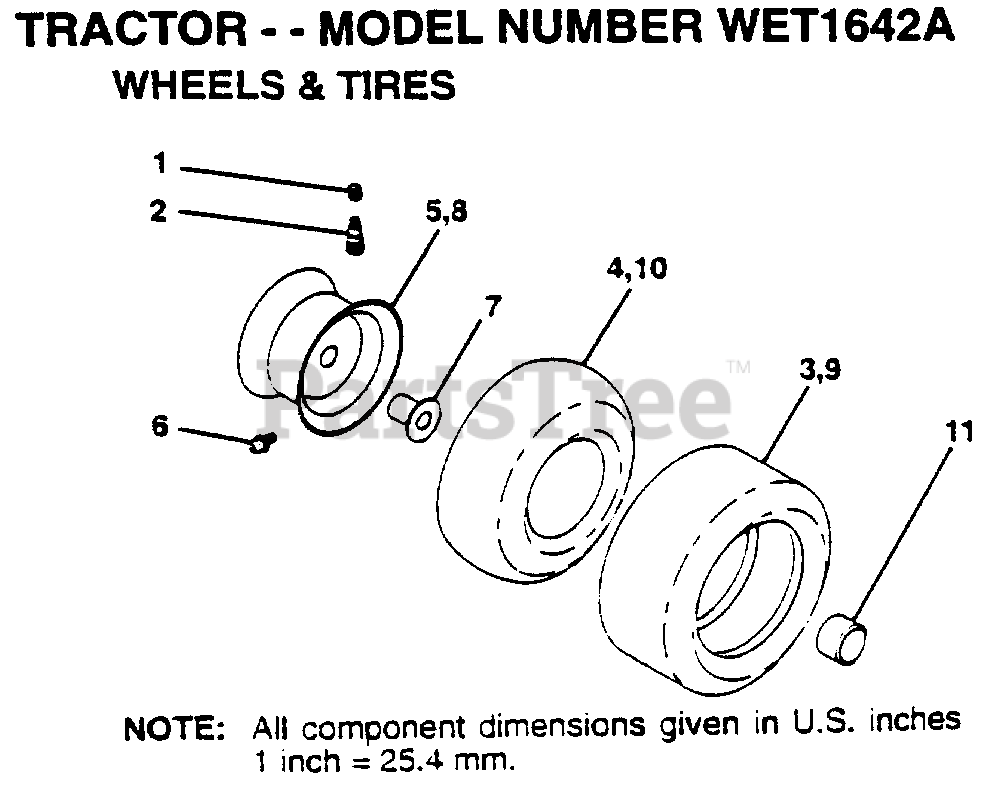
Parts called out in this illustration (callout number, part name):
1	VALVE CAP
2	VALVE STEM LT
4	TUBE.5.3/4.5/6
5	"RIM.ASM.6""FRONT"
6	FITTING LT
7	"FLANGE, BEARING"
8	"RIM.ASM.8""REAR"
9	TIRE.20X8-8
10	TUBE.18X9.5-8
11	HUB CAP
